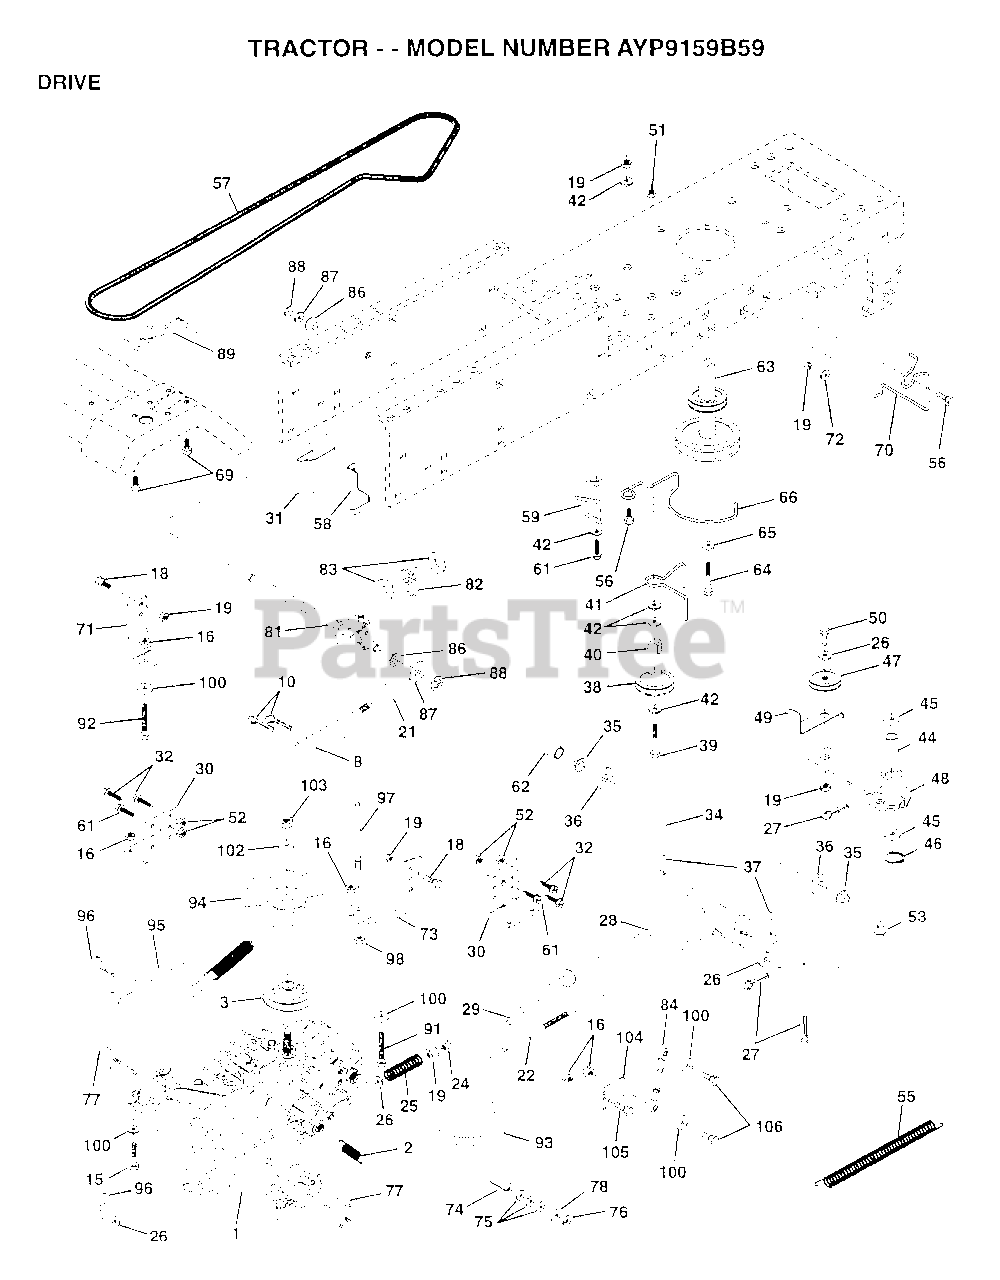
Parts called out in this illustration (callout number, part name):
2	SPRING RET BRAKE
3	PULLEY.TRANSAXLE
8	ROD SHIFT FEND LT
10	PIN COTTER 1/8
15	BOLT HEX
16	NUT
18	BOLT
19	NUT
21	KNOB T (1/2-HOLE)
22	ROD.BRAKE.HYDRO.
24	NUT
25	SPRING ROD LT
26	WASHER
27	COTTER PIN
28	ROD.BRAKE.PARK.LT
30	TRANSAXLE MTG BKT
31	"KEEPER,BELT LH T"
32	BOLT
34	SHAFT.PEDAL.FOOT
35	NYLON BEARING
36	WASHER LT
38	PULLEY.IDLER.FLAT
39	BOLT
40	SPACER T
41	BELT KEEPER LT
42	WASHER
44	"LY, BEARING"
45	WASHER LT
46	KLIP RING
48	ARM IDLER
49	RETAIN BELT
53	"LINK, CLUTCH T"
55	"SPRING, RETURN LT"
57	"BELT.GD DRV 82"""
58	KEEPER BELT LH
59	KEEPER BELT CNTSP
61	SCREW
62	PEDAL COVER T
63	PULLEY.ENGINE
64	BOLT
65	LOCKWASHER
66	KEEPER.BELT.ENG.L
69	SCREW HEXWSH H-L
70	KEEPER BELT ENG
71	STRAP TORQ LH HYD
72	WASHER
73	STRAP TORQ RH HYD
74	SPACER SPLIT
75	WASHER
76	E-RING LT
77	SQUARE KEY
78	WASHER
82	"SPRING,TORSION"
83	WASHER
84	ROD.TIE.BALL.4.75
86	BUSHING
87	WASHER D
88	KLIP RING
92	HEX BOLT
93	"LINE FUEL HYD 4"""
94	"FAN 7"" HYDRO"
96	RETAINER M
97	BOLT KEEPER RH
98	NUT
100	WASHER M
102	WASHER BELLEVILLE
104	ARM CONTROL HYDRO
105	SCREW CAP 5/16-18
106	BOLT
